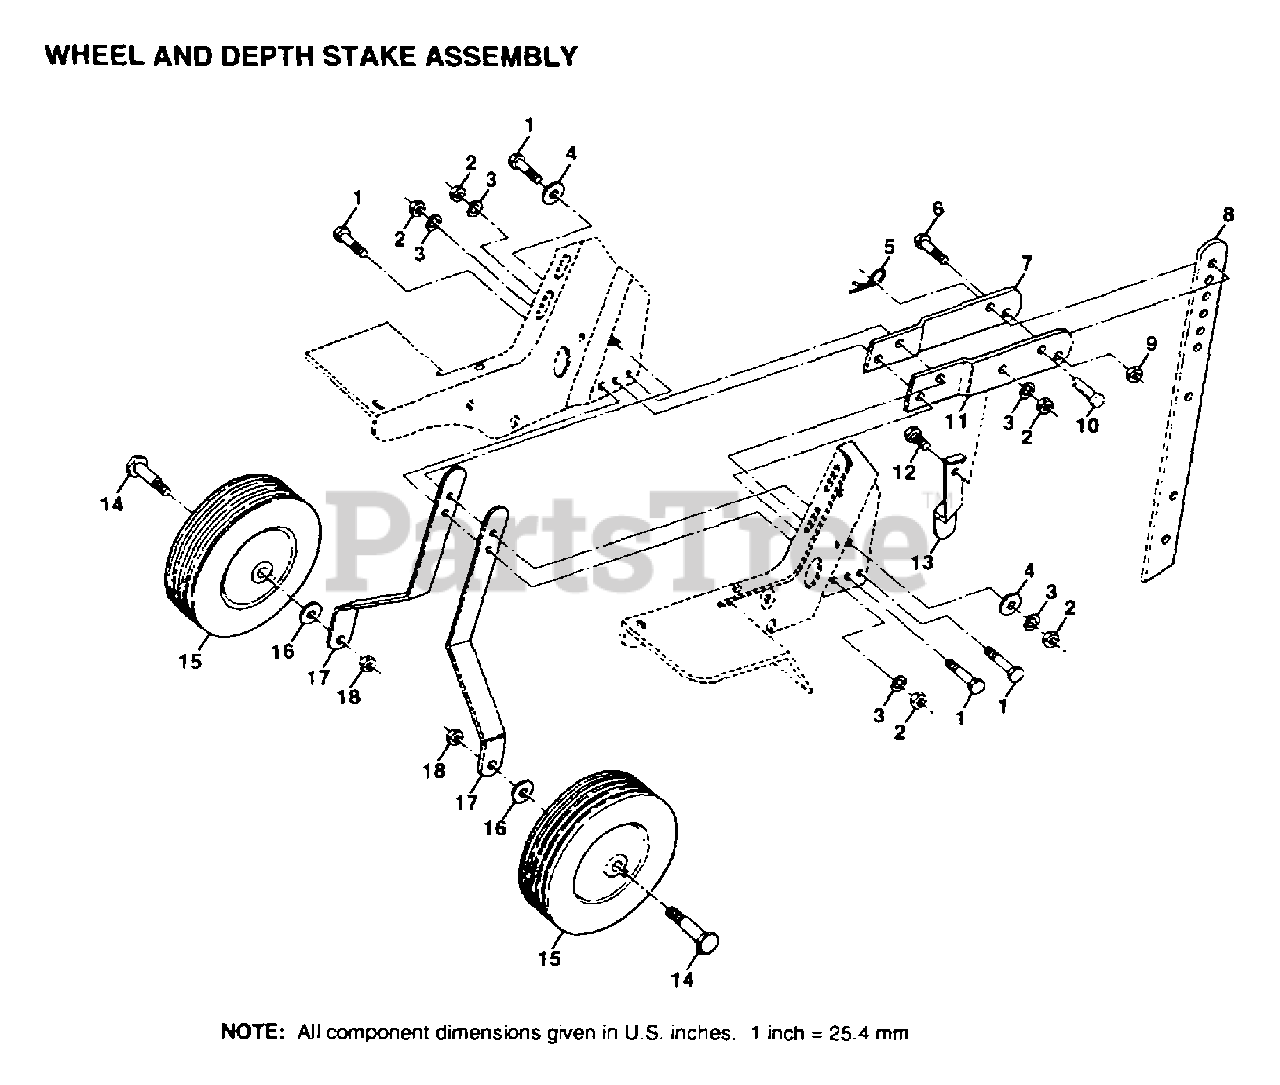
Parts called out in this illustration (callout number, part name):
2	NUT.HEX.5/16-18
3	LOCKWASHER
4	WASHER
5	SPRING.RETAINER
6	BOLT.3/8-24X1-1/2
7	STAKE.SUPT.TILLER
9	GRIPCO NUT
10	DRILLED RIVET RT
12	BOLT
13	STAKE SPRING CT
14	BOLT SHOULDER
16	WASHER
